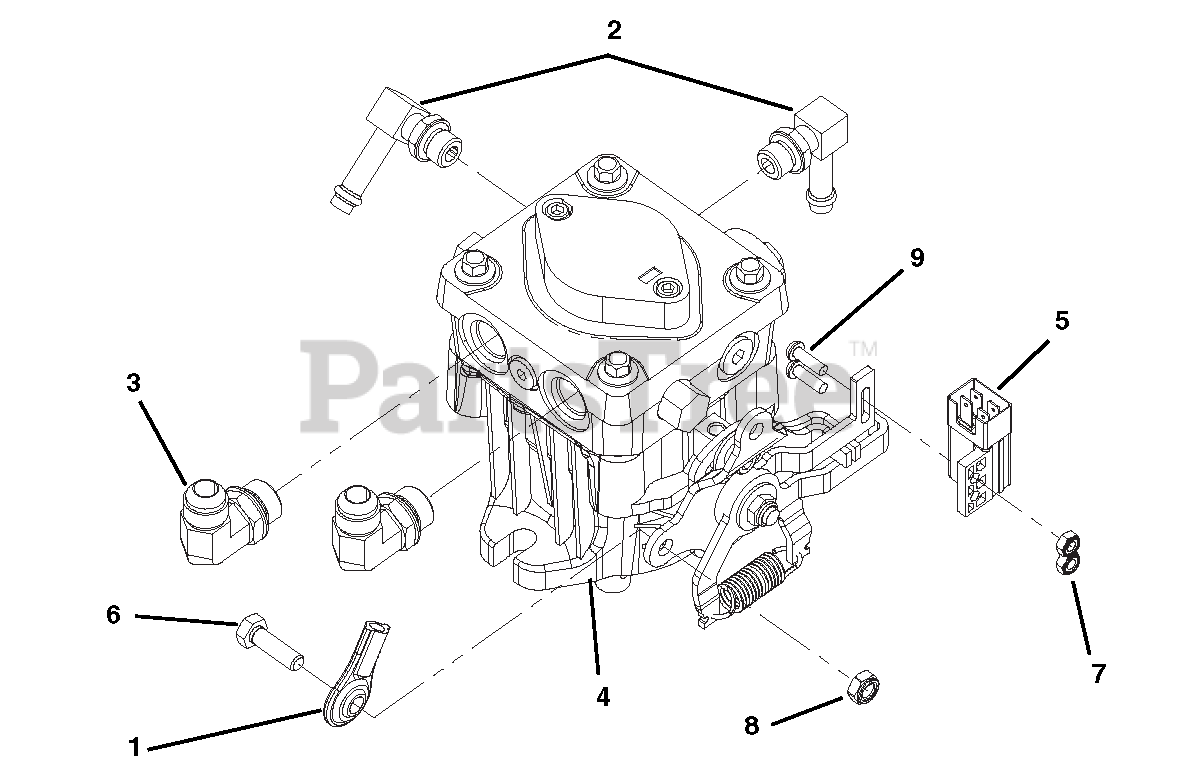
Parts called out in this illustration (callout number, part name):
1	ALIGNABALL, 5/16 RH THREAD
2	FTG, 90 9/16MOR X 3/8HOSE
3	FTG, 90 ADP JIC-ORB 6801-08-08
4	PUMP, HYD RH
5	SWITCH, PLUNGER DP - N.O.-N.C.
6	BOLT, 5/16-18X1.00 HEX 5 Y
7	LOCKNUT, 10-24 NYLOC Y
8	LOCKNUT, 5/16-18 NYLOC Y
9	SCREW, 10-24X.625 PAN PHL MACY
NS	KIT, PUMP SEAL BDP10 & 12 S/O
